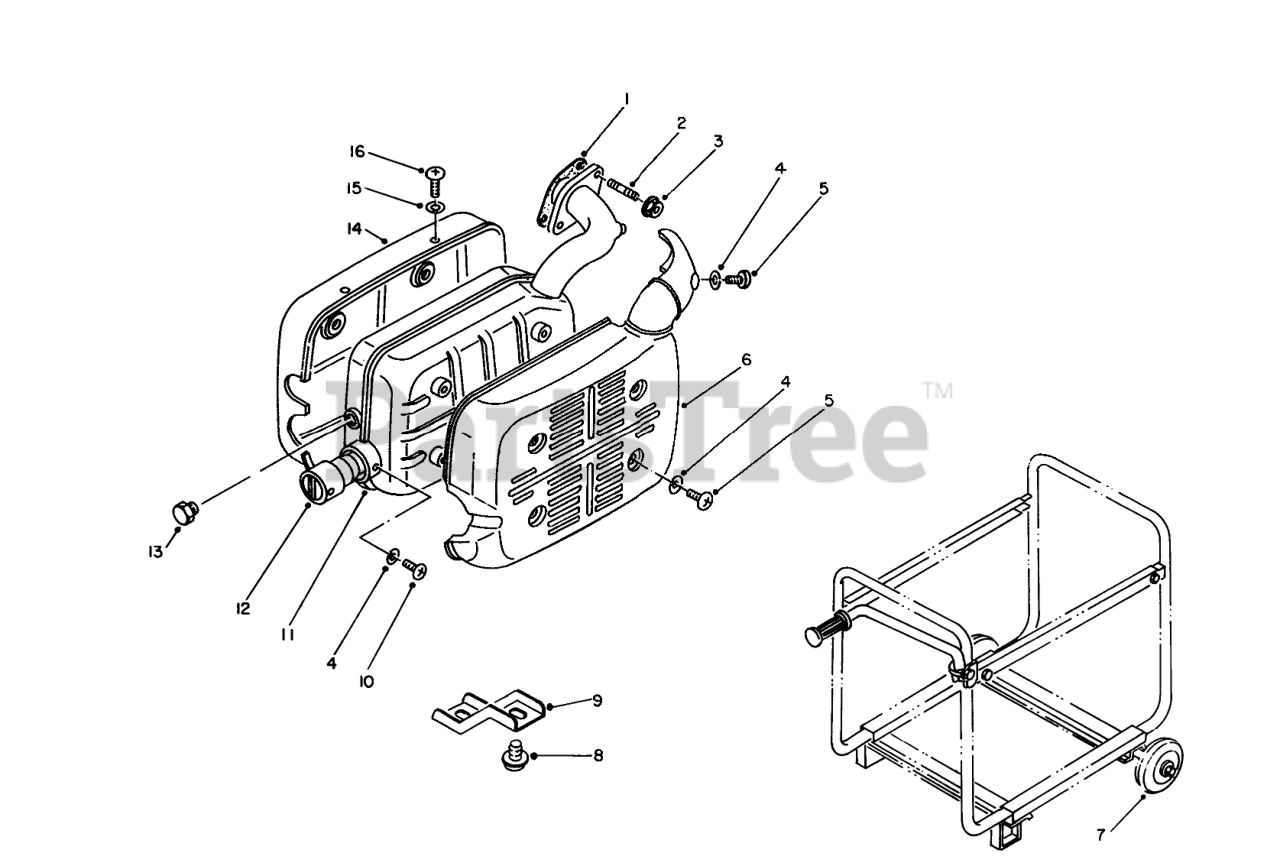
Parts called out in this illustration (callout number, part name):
1	Gasket-Exhaust
2	Stud Bolt
4	LOCKWASHER
5	SCREW
6	Cover-Front
7	Wheel Assembly (Optional)
9	Bracket
10	Screw
11	MUFFLER ASSM
12	Cleanout Tube
13	Drain Plug
14	Cover-Rear
15	Lockwasher
16	Screw
